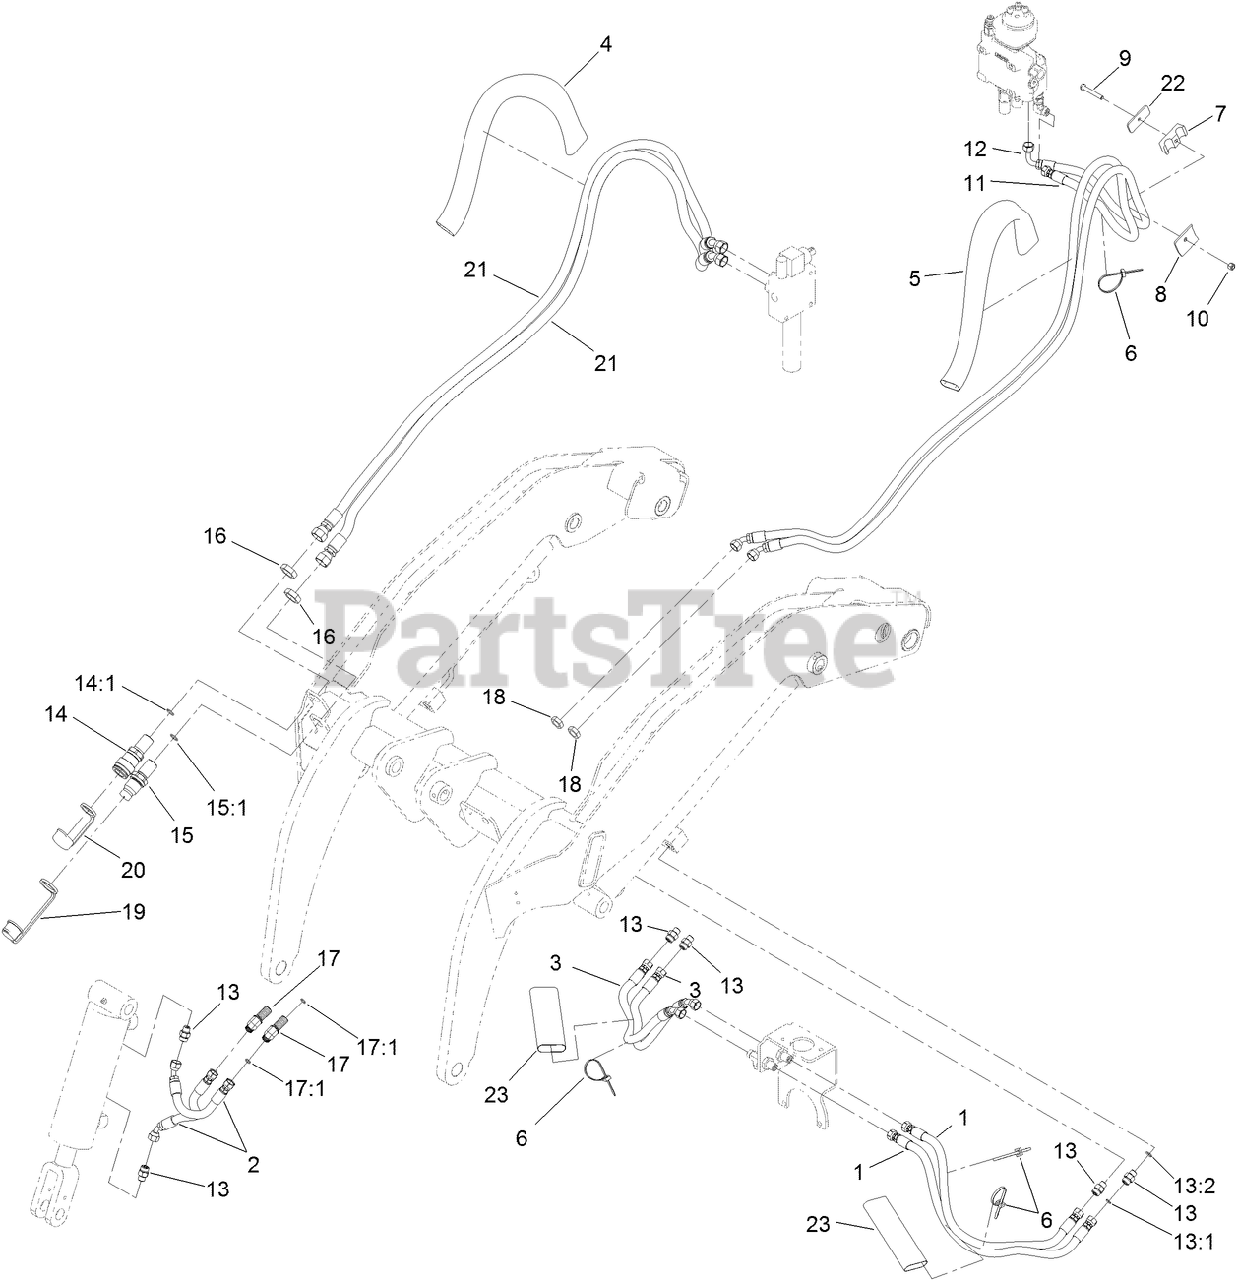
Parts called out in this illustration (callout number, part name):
1	HYD HOSE ASM
2	HOSE-HYD
3	HYD HOSE ASM
4	SLEEVE-PROTECTIVE
5	SLEEVE-PROTECTIVE
6	TIE-CABLE
7	CLAMP-TUBE
8	PLATE-HOLDDOWN, HOSE
9	BOLT-TAP, HH
10	NUT-LOCK, NI
11	HOSE-HYD
12	HOSE-HYD
13	FITTING-STRAIGHT
13:1	O-RING
13:2	O-RING
14	BULKHEAD COUPLER ASM
14:1	O-RING
15	BULKHEAD NIPPLE ASM
15:1	O-RING
16	NUT-LOCK, BULKHEAD
17	ELBOW-BULKHEAD, 45 DEG
17:1	O-RING
18	NUT-LOCK
19	CAP-DUST, NIPPLE
20	CAP-DUST, COUPLER
21	HOSE-HYD
22	PLATE-CLAMP, HOSE
23	SLEEVE-PROTECTIVE
